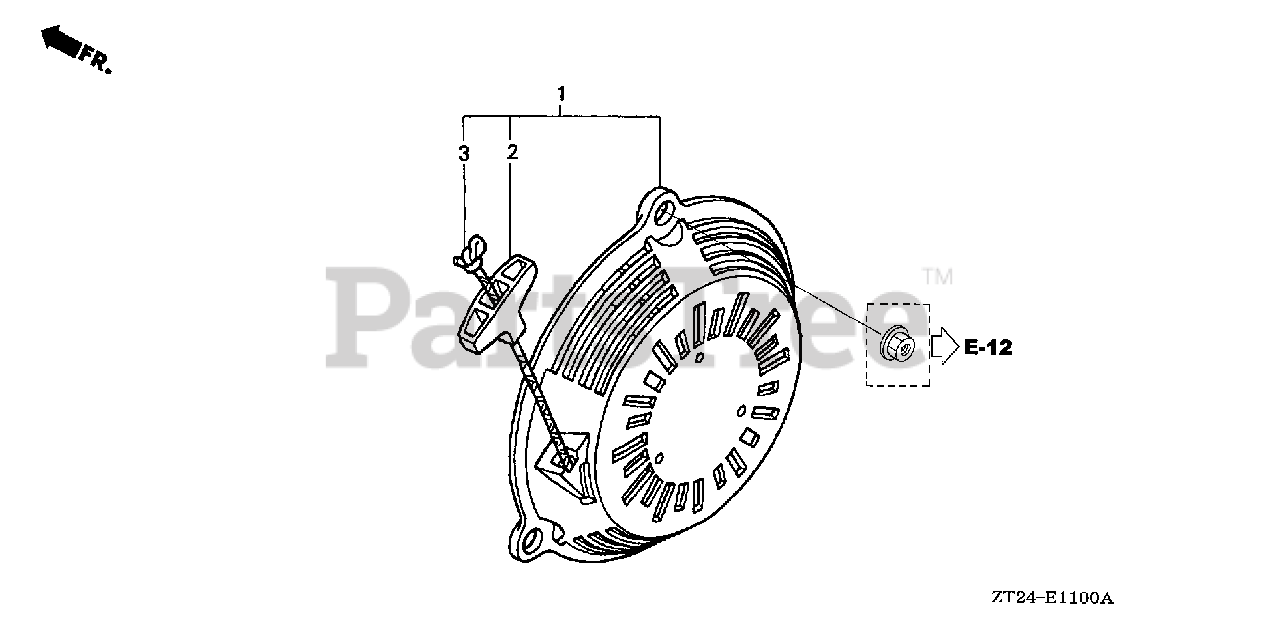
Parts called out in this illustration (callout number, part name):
1	STARTER ASSY., RECOIL *NH1* (BLACK)
1	STARTER ASSY., RECOIL *R280* (POWER RED)
2	GRIP, STARTER
3	ROPE, RECOIL STARTER
